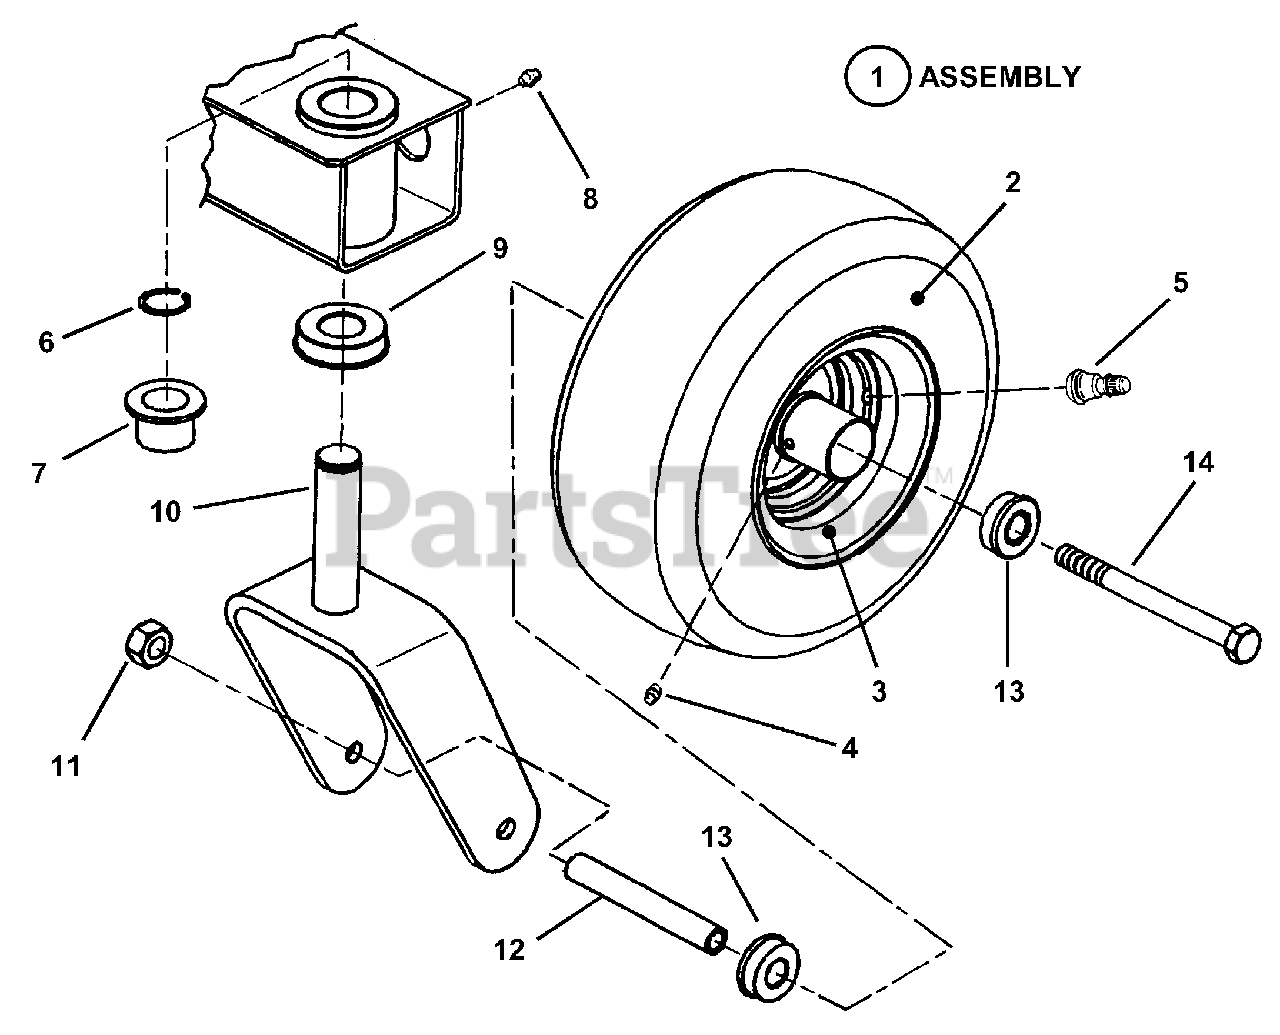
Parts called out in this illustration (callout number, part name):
1	ASSEMBLY, Front Wheel & Tire (Complete)
2	TIRE, 11 x 4.00-5, Smooth Tread
3	RIM, Caster Wheel
4	FITTING, Lube
5	VALVE, Air (Snap-in)
6	RING, 1" External Retaining
7	BUSHING, Caster
8	LUBE FITTING, Straight (press-fit for .187 dia. Hole)
9	BEARING, Flanged 1 x 2 x 5/8"
10	CASTER, Pivot Yoke
11	NUT, 7/16-14 Hex Center Lock
12	TUBE, 5/8 O.D. x 14 Ga. x 4.51
13	BEARING, Ball 5/8 x 1-3/8"
14	SCREW, 7/16-14 x 6" Hex Head Cap, Grade 5
